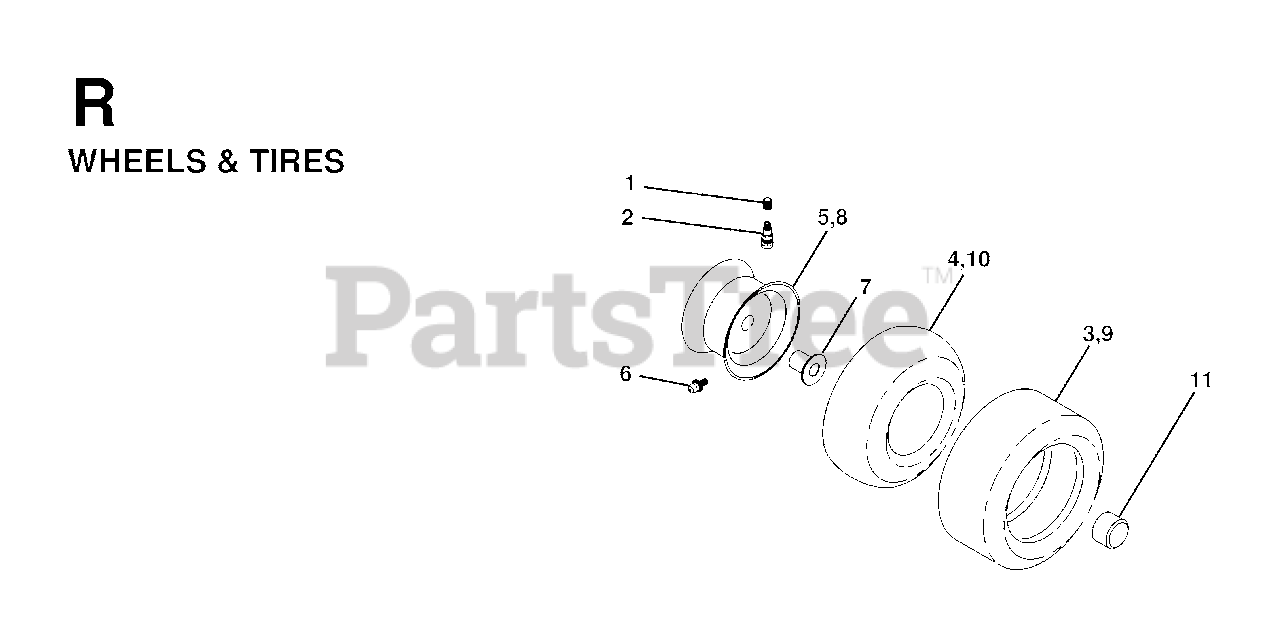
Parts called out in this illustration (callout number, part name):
1	VALVE CAP
2	VALVE STEM LT
3	TIRE HEAVY DUTY
4	TUBE.5.3/4.5/6
5	RIM ASM 6" FRONT SILVER
6	FITTING LT
7	BEARING T
8	RIM ASM 8" REAR SILVER
9	TIRE.TS.20X10-8
10	TUBE
11	CAP-HUB FRONT LT
